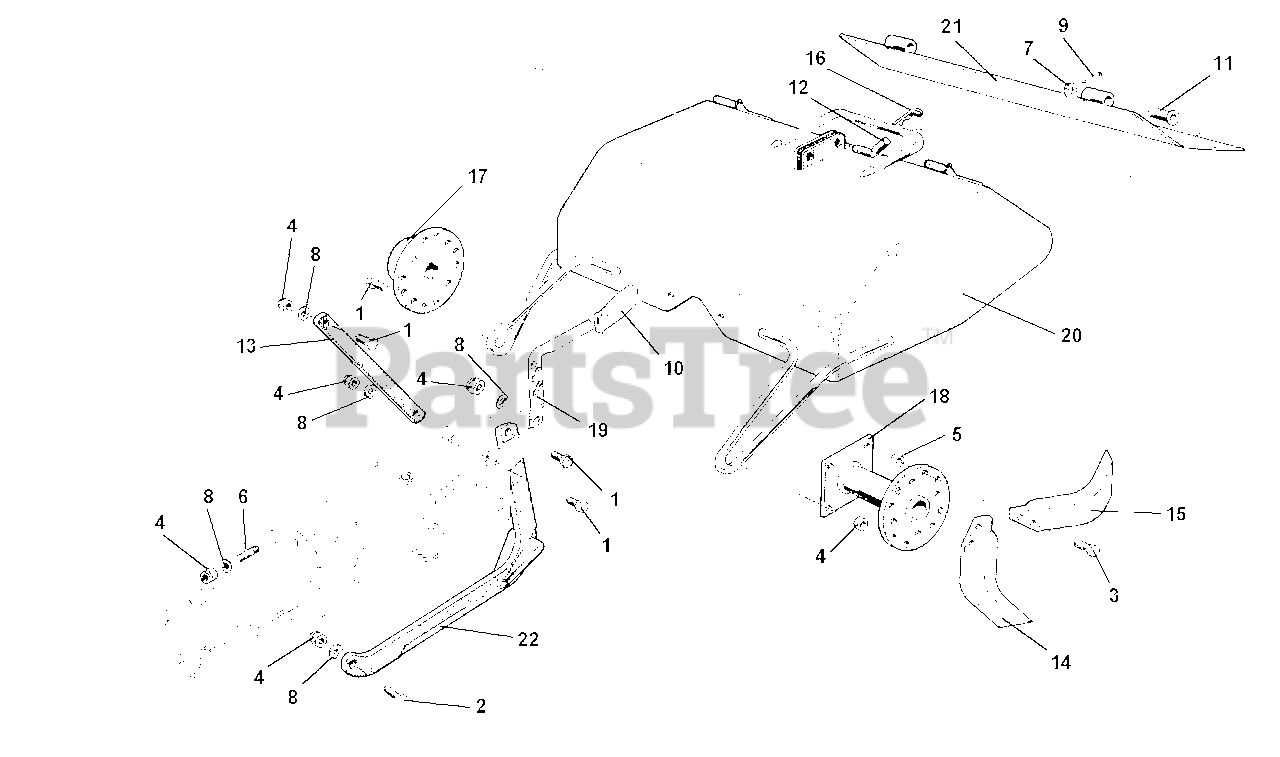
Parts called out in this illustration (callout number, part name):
1	SCREW M8 X 25
2	SCREW TE M8 X 30
3	SCREW TE M10 X 25 UNI 5739-8G
4	NUT, SELF LOCKING M8
5	NUT, SELF LOCKING M10
6	STUD M8 X 32 X 14 X 14
7	WASHER P10.5 X 18
8	WASHER, LOCK 8.4
9	PIN, COTTER A 3 X 20 UNI 1336
12	ADJUSTMENT PIN
14	KNIVE WIDE LEFT
15	KNIVE WIDE RIGHT
17	KNIVE HOLDER FLANGE
18	SPACER KNIVES
20	ROTARY HOE ASSEMBLY
21	ROTARY HOE FLAP
22	CENTRAL KNIVE
